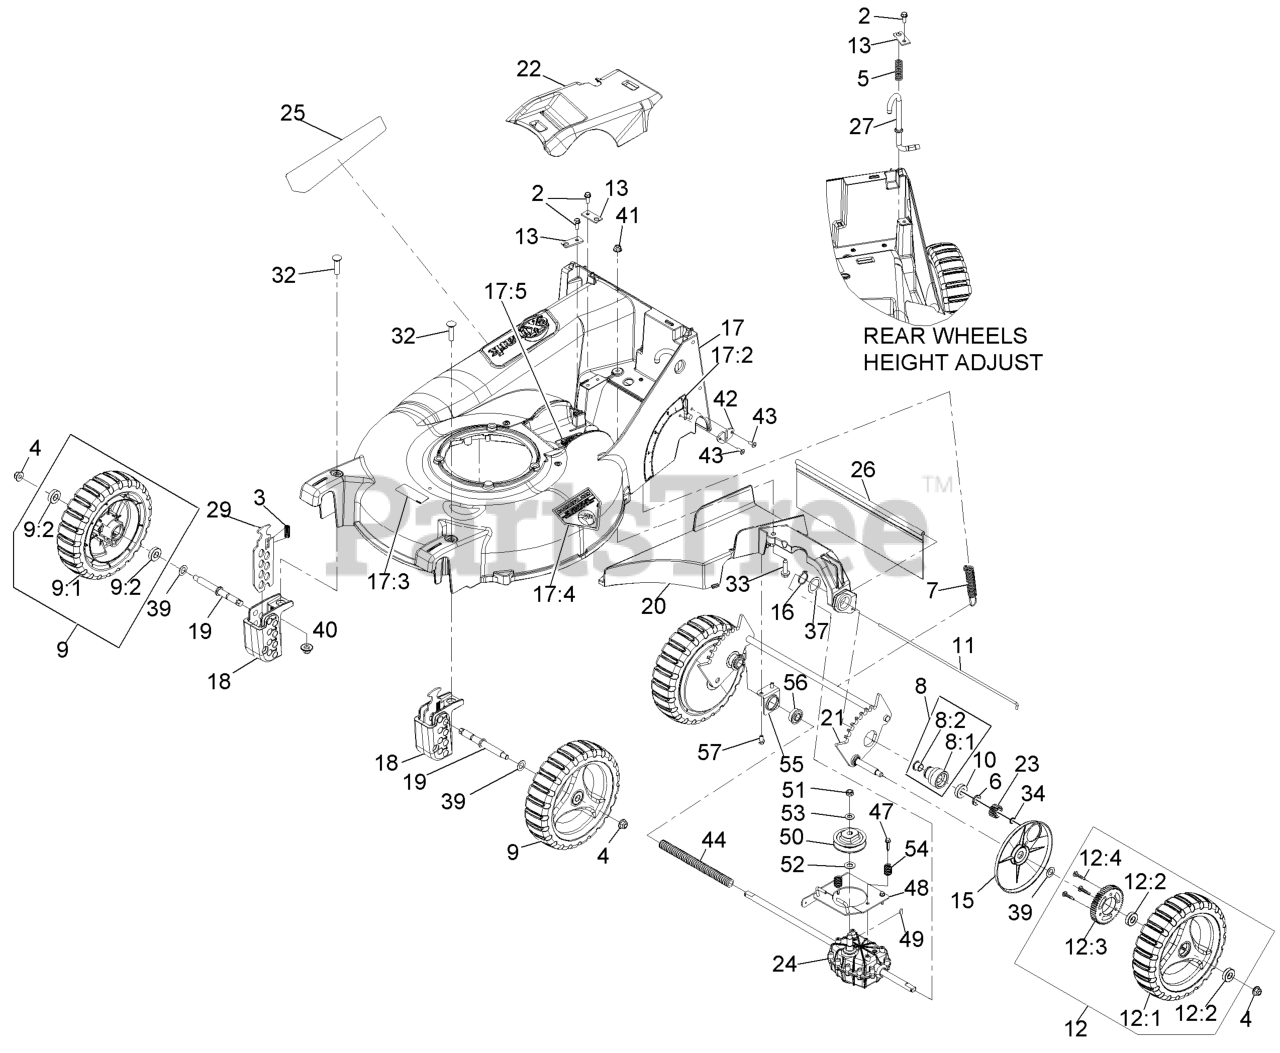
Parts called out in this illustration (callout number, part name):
2	SCREW-HWH
3	SPRING-COMPRESSION
4	NUT-HF, NI
5	SPRING-COMPRESSION
6	SPACER-BUSHING
7	SPRING-EXTENSION
8	HOUSING ASM
8:1	HOUSING-BEARING
8:2	BEARING-FLANGE
9:2	BEARING-BALL
10	BEARING-BALL
11	ROD,SHIELD
12:2	BEARING-BALL
12:4	SCREW-DRIVE
13	BRACKET,MOUNT
15	COVER,GEAR
16	RING-RETAINING
17	DECK W/DECALS
17:2	DECAL-HEIGHT OF CUT
17:3	DECAL-BLADE
17:4	DECAL-DANGER
17:5	DECAL-COVER MISSING
18	BLOCK,FRONT QUADRANT
19	AXLE-WHEEL
20	BRACKET-TRANSMISSION AND
21	WLD,REAR AXLE P21
22	COVER,BELT
24	TRANSMISSION-HD, 4.5/1
25	DECAL-COMM 21 S-SERIES
26	SHIELD-TRAILING P21
27	ROD-HEIGHT ADJ P21
29	PLATE, FRONT HEIGHT
32	SCREW-CARR
33	SCREW-HWHTF
34	RING-RETAINING
39	WASHER-PLAIN
40	Nut-Nyloc 3/8-16 Flg
41	NUT-HF, NI
42	PLATE,WEAR
43	RIVET-BLIND
44	COVER-SHAFT-DRIVE
47	SCREW-SPECIAL
48	TRANSMISSION PLATE ASM
49	KEY-WOODRUFF
51	NUT-HEX
52	WASHER-THRUST
53	WASHER-FLAT
54	SPRING,COMPRESSION
56	BEARING-BALL
57	SCREW-HWH
